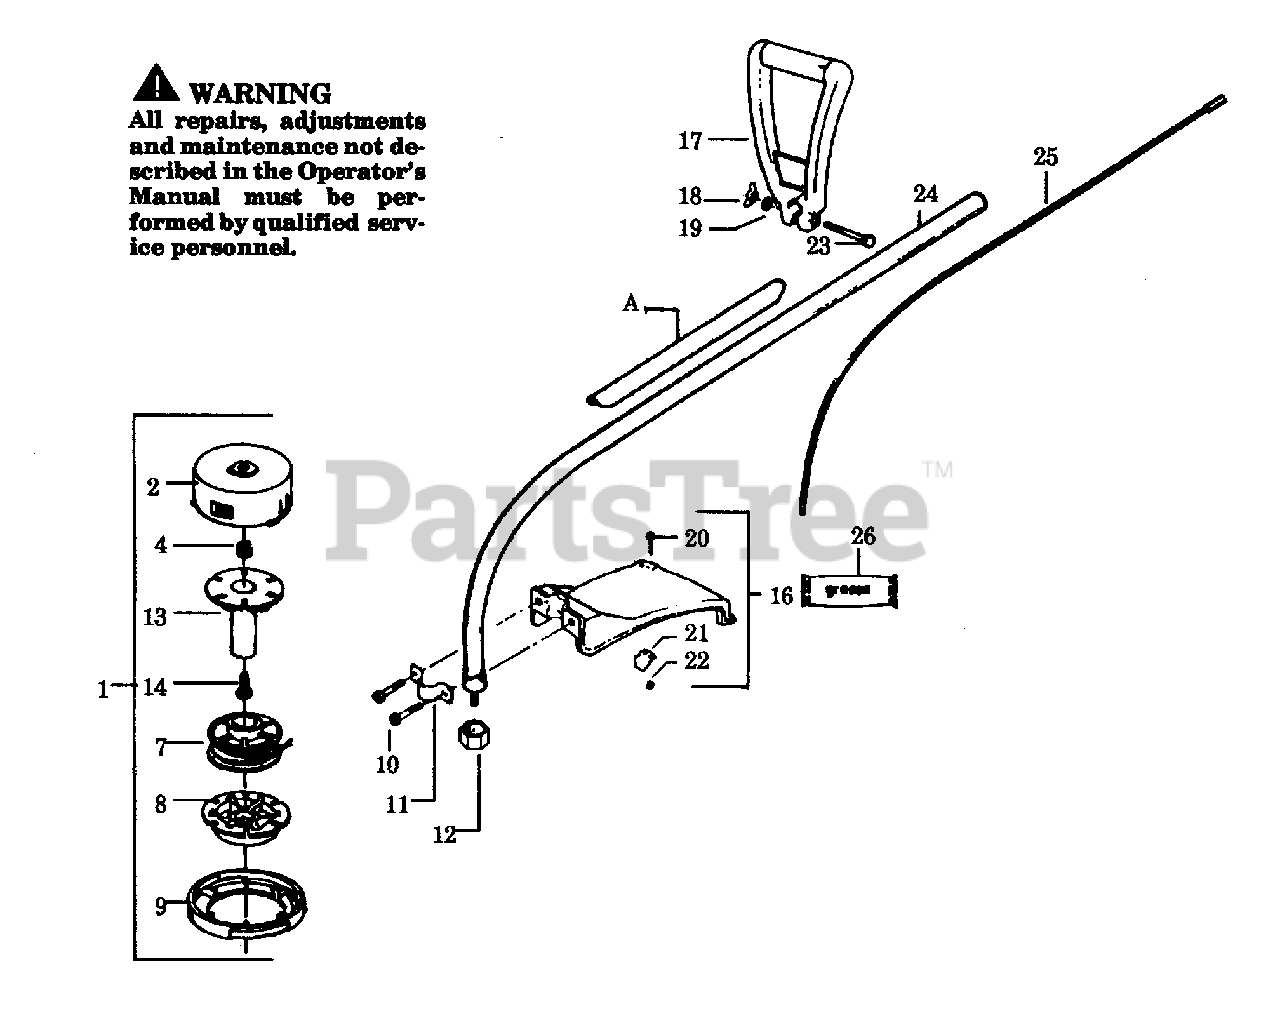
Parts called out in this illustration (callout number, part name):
1	Cutting Head Ass'y. (Inc.2-9)
2	Hub w/Line Saver
4	Spring
7	Spool w/Line
8	Release Button
10	Screw
11	Shield Bracket
12	Dust Cup
13	Spool Post
14	Screw #10-24x5/8
16	Shield Kit Ass'y.
17	Assist Handle
18	Wing Nut
20	Screw #10-24x1
21	Line Limiter
22	Nut
24	Drive Shaft Ass'y (Inc. 12)
25	Flexible Shaft Ass'y.
26	Flex Shaft Lube
A	Safety Label Decal
